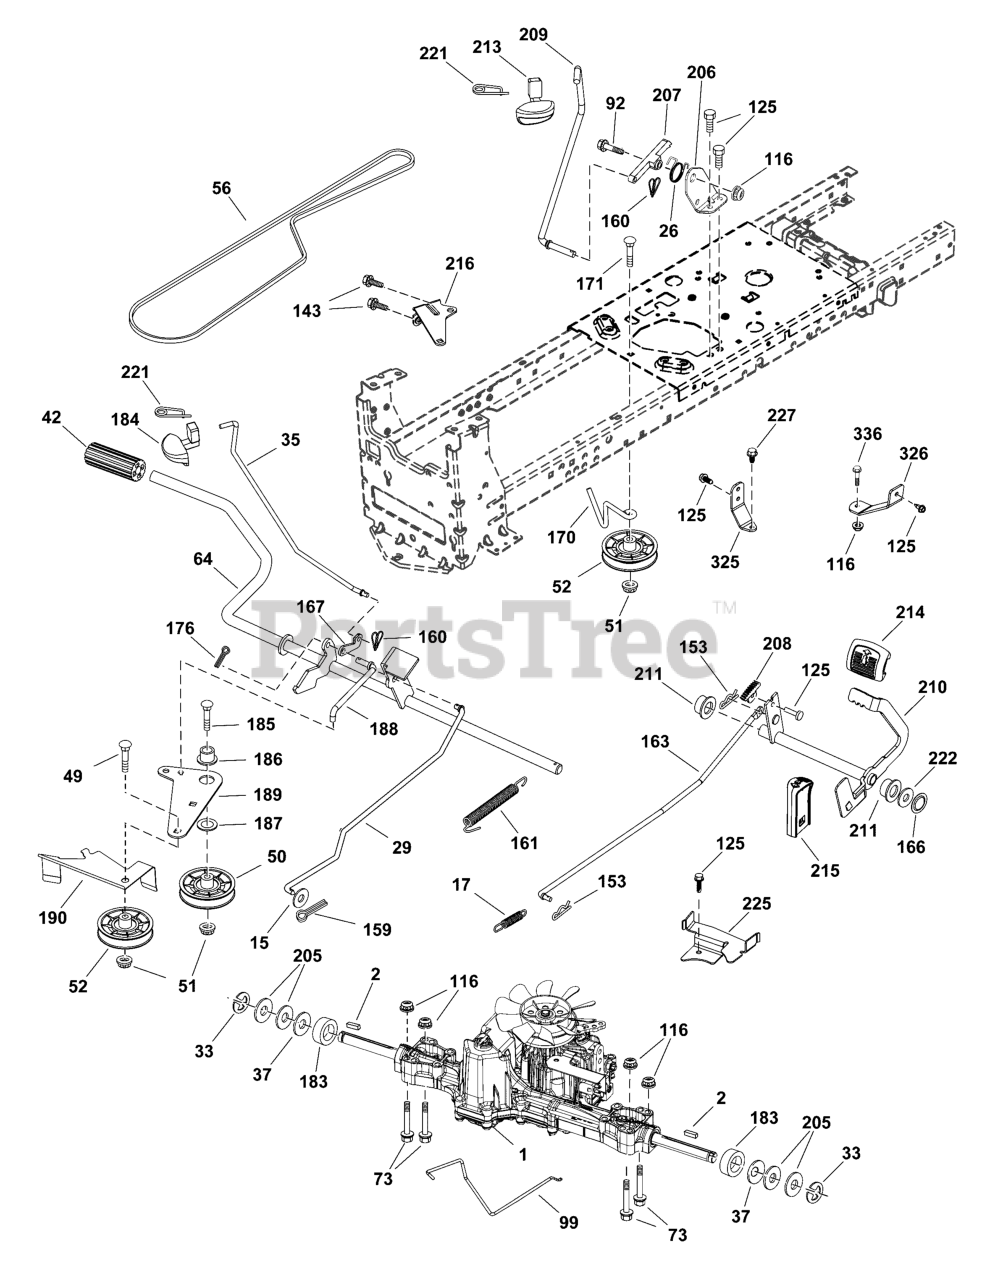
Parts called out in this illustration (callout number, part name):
1	TRANSAXLE, TUFFTORQ K46 BT (426120)
15	Washer 13/32 x 13/16 x 16 Ga.
17	Spring Brake
26	Spring Return Cruise
29	Rod, Brake
35	ROD, Park Brake
37	WASHER, Hardened
42	COVER, Foot Pedal
50	Pulley Idler Flat
51	NUT, 3/8-16, Lock
52	Idler V-Groove
56	V-Belt Drive
64	Shaft Asm. Pedal Brake Control
73	Bolt 5/16-18 x 2-1/2 Gr. 5
92	Bolt 5/16-18 unc x 1.25
99	Rod Bypass
116	Nut, Lock Hex Flange 5/16-18 Unc
125	Screw 5/16-18 X 3/4 Smgml Tap/Bl
143	SCREW, 5/16-18 X 1/2, Thread Roll
153	RETAINER, Spring
159	Pin Cotter 1/8 x 3/4
160	RETAINER CLIP
161	Spring Return Clutch
163	Rod Control Pedal
166	Nut Push
167	Latch Brake Parking
170	Keeper Belt Centerspan
171	Bolt RDHD SQNK 3/8-16 unc x 2
183	Spacer Split
184	HANDLE, Parking Brake
185	BOLT, 3/8-16 X 2-3/4, GR 5, Carriage
186	Spacer Retainer
188	Link Clutch Ground Drive
189	Bellcrank Ground Drive
190	Keeper Bellcrank Ground
205	Washer 25/32 x 1-5/8 x 16 Ga.
206	Bracket Mount Latch
207	LATCH, Control
208	Gear Sector Control
209	ROD, Cruise Control
210	Rocker Asm. Pedal
211	Bushing Brake Shaft
213	KNOB, Cruise Control
214	Pedal Forward
215	Pedal Reverse
216	Bracket Pulley Idler
221	Retainer Spring Clip Handle
222	WASHER, 21/32 x1-1/4 10 Ga.
225	Keeper Belt Trans.
227	SCREW, 5/16-18 x 3/4 Thred Roll
325	STRAP, Torque
326	BRACKET, Torque
336	KIT, Rope Guide
